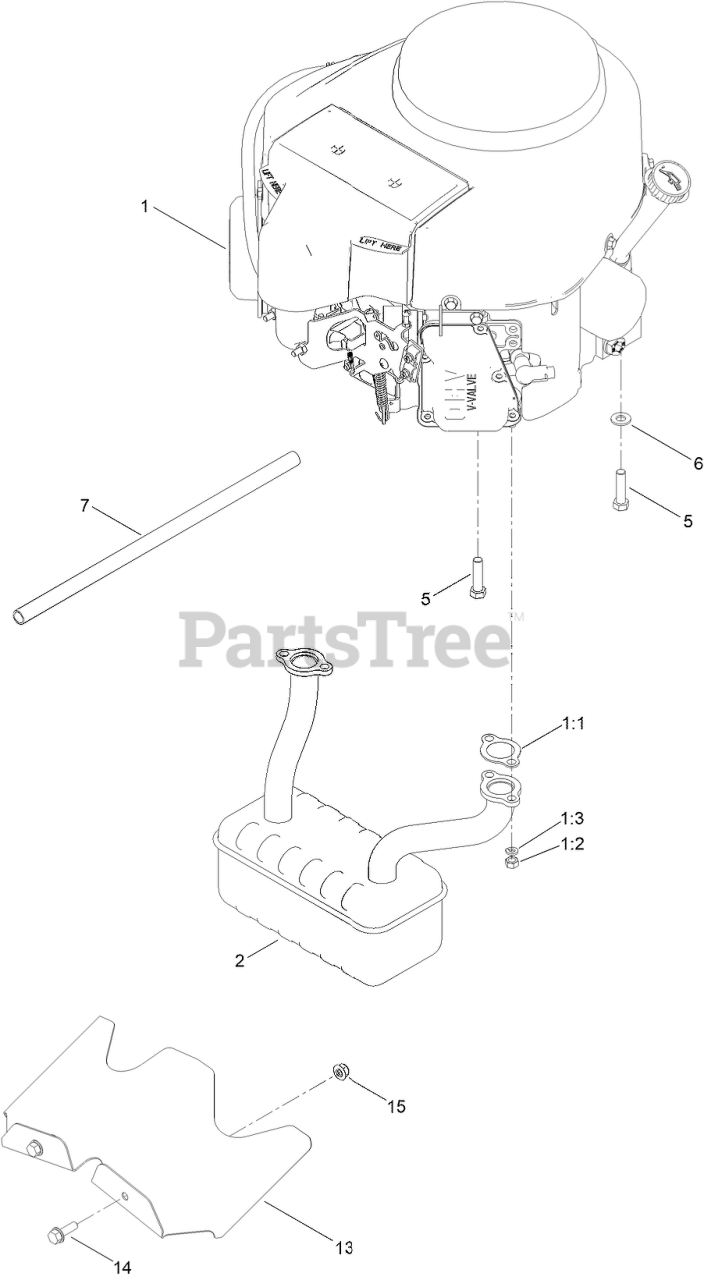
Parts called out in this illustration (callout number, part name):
1:1	GASKET-EXHAUST
1:3	WASHER-LOCK
2	MUFFLER
5	BOLT-HH
6	WASHER-FLAT
7	TUBE-DRAIN, OIL
13	SHIELD-HEAT
14	SCREW-HHF
15	NUT-HF, NI
